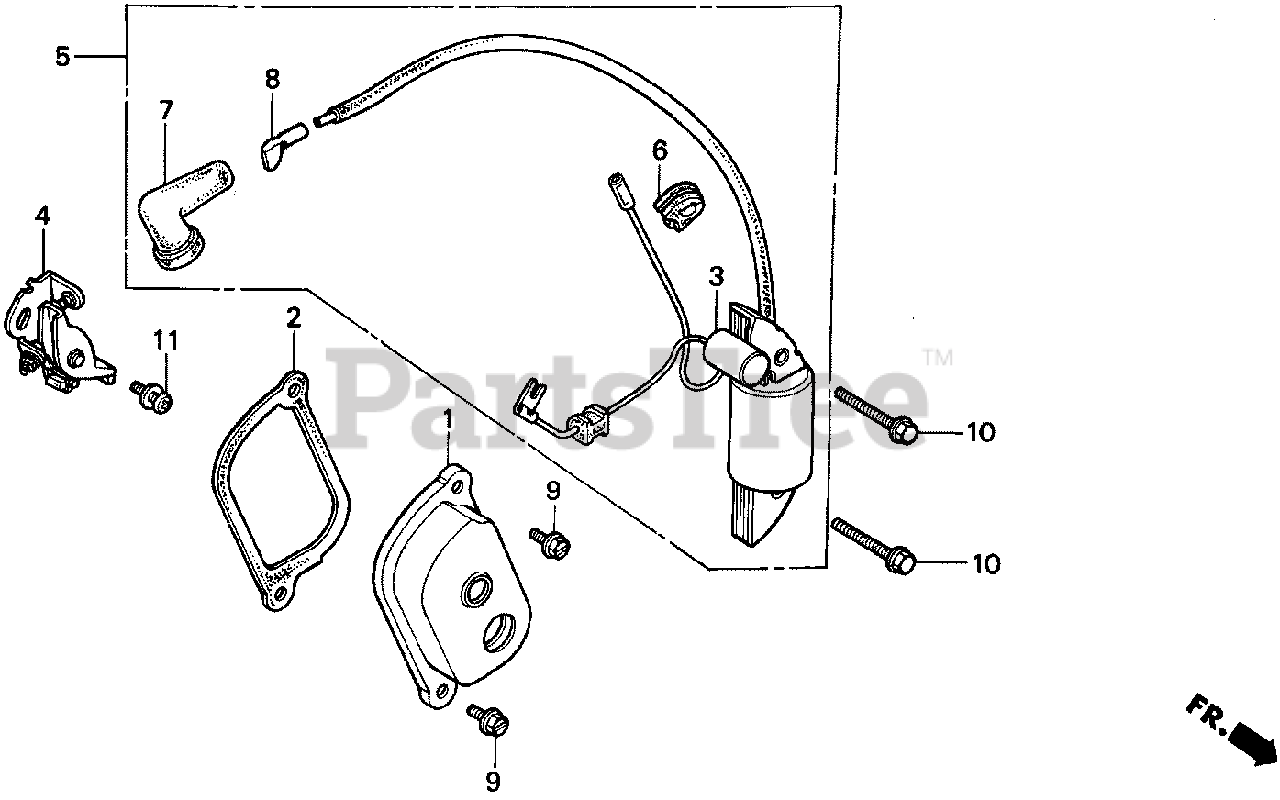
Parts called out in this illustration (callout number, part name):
1	COVER, POINTS
2	GASKET, POINT COVER
2	GASKET, BREAKER COVER
3	CONDENSER
4	POINTS ASSY.
5	COIL ASSY., IGNITION (NOT AVAILABLE)
6	GROMMET, WIRE
7	CAP, IGNITION (SUMITOMO)
7	CAP, IGNITION (TOYO)
8	TERMINAL, PLUG
9	BOLT, FLANGE (5X10)
10	BOLT, FLANGE (5X25)
11	SCREW-WASHER (5X12)
